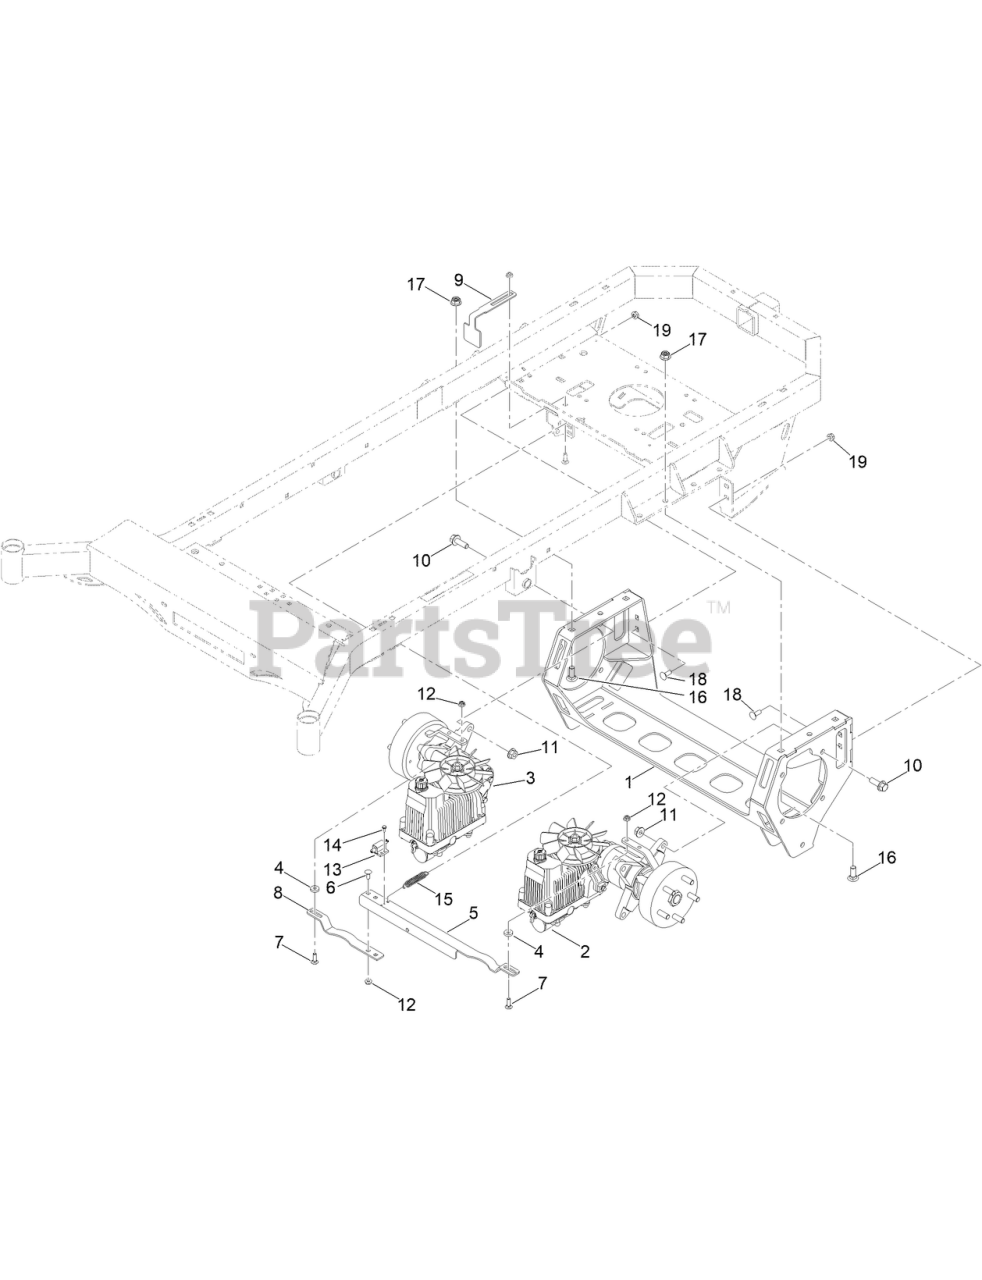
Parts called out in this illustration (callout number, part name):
1	HYDRO FRAME ASM
2	HTE10 LT SIDE HYDROST TRANSM FOR RZ HUB
3	HTE10 RT SIDE HYDROST TRANSM FOR RZ HUB
4	.312 ID X .875OD X .1875 THK F/W NYL
5	MWR PARK BRAKE BRKT LT PAINT
6	BOLT-CARR
7	BOLT-CARR
8	MWR PARK BRAKE BRKT RT PAINT
9	STAND TRANS BRAKE INTERLOCK BRKT PAINT
10	SCREW-HHF
11	NUT-HHF
12	NUT-HF, NI
13	NO PLUNGER LIMIT SWITCH
14	8-32 X 1/2 IND. HWH SLOT TYPE F TCS ZINC
15	MWR BRAKE PEDAL RELEASE SPRING
16	SCREW-CARR,PATCH
17	1/2-13 HEX FLANGE 2-WAY REV CNTR L/NYZ
18	3/8-16 X 1 CARRIAGE BOLT YZ GR.8
